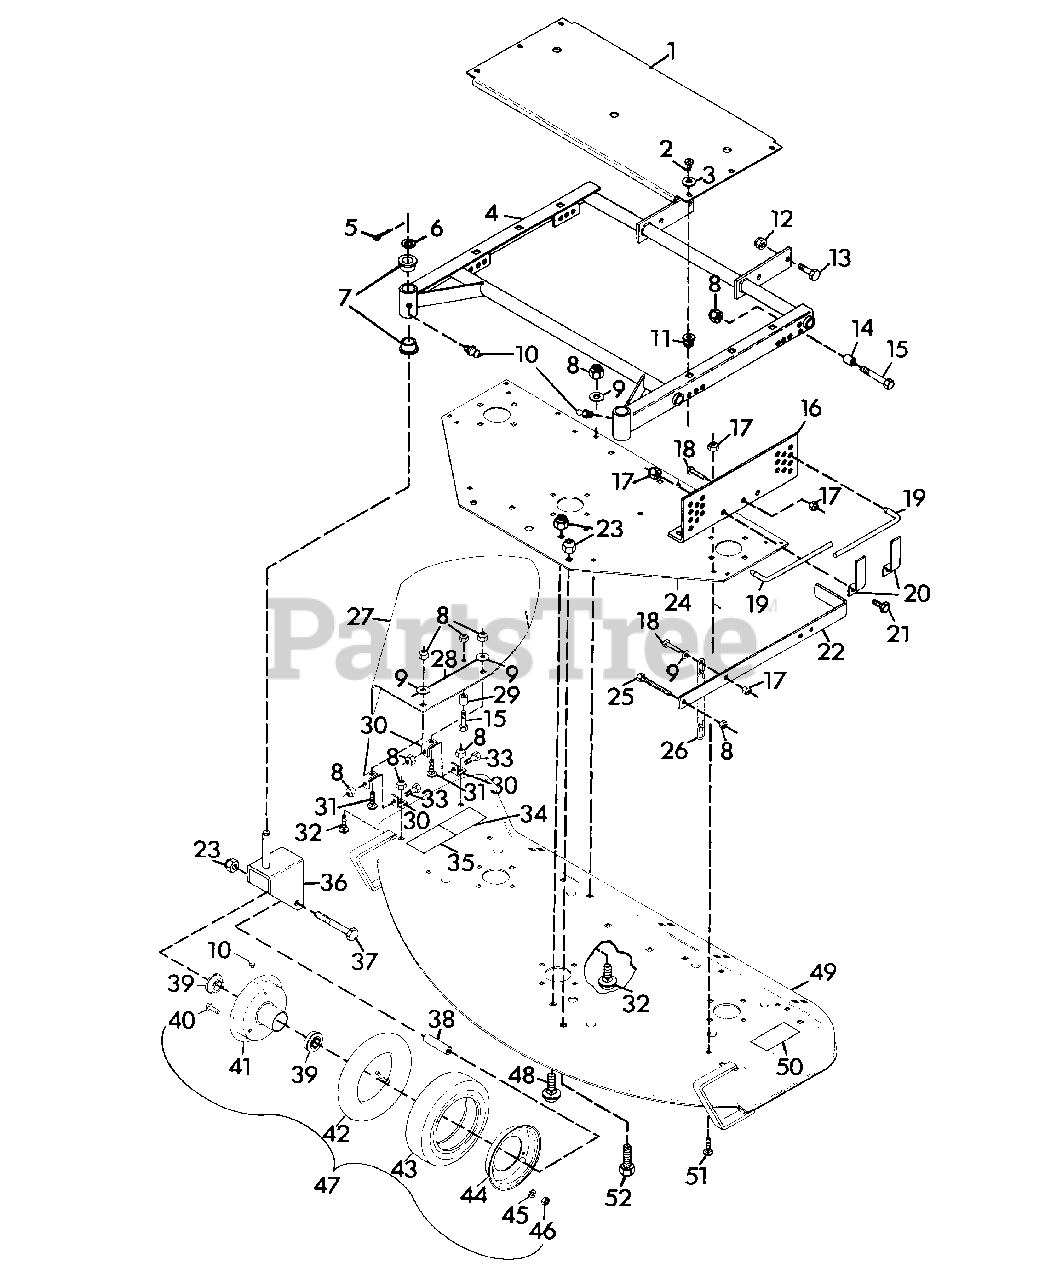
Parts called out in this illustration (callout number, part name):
1	GUARD, 50" MOWER BELT
2	SCREW, TAPPING 1/4-20X.625 P/HD
3	WASHER, FLAT .281X.625X.065
4	WELDMENT, MOWER FRAME
5	PIN, COTTER .187X1.50
6	RACE, BEARING THRUST
7	BUSHING, PIVOT
8	NUT, LOCK 3/8-16
9	WASHER, FLAT .406X.812X.065
10	FITTING, LUBE 1/4-28
11	GROMMET, PLASTIC
12	NUT, LOCK 5/8-11
13	BOLT, HEX 5/8-11X1.50
14	BUSHING .391X.622X.670
15	BOLT, HEX 3/8-16X1.50
16	BRACKET, MOWER SUPPORT L.H.
16	BRACKET, MOWER SUPPORT R.H.
17	NUT, LOCK 5/16-18
18	BOLT, HEX 5/16-18X1.00
19	PIN, MOWER LOCKING
20	TAB, PIN LOCKING
21	BOLT, HEX 5/16-18X.75
22	BAR, LIFT
23	NUT, LOCK 1/2-13
24	ASSEMBLY, 50" SUPPORT PLATE
25	BOLT, HEX 3/8-16X2.00
26	CHAIN, HEIGHT ADJUSTMENT
27	SHIELD, SAFETY EXT. 50" MOWER
28	STRIPE
29	STOP, CHUTE
30	TAB, SPRING
31	BOLT, 3/8-16X1.00 RD HD SQ NK
32	BOLT, CARRIAGE 3/8-16X.75
33	BOLT, HEX 3/8-16X.875
34	DECAL, DANGER HAND
35	DECAL, WARNING EYE
36	WELDMENT, CASTER FORK
37	BOLT, HEX 1/2-13X5.00
38	BUSHING, WHEEL .520X.750X3.312
39	BEARING, GAUGE WHEEL
40	BOLT, HEX 3/8-24X.75
41	WHEEL, HALF WITH TUBE
42	TUBE, INNER
43	TIRE, GAUGE WHEEL
44	WHEEL, HALF PLAIN
45	WASHER, LOCK 3/8 SP HEAVY
46	NUT, HEX 3/8-24
47	WHEEL, GAUGE
48	BOLT, 1/2-13X1.00 RD HD SQ NK
49	WELDMENT, 50" DECK
50	DECAL, DANGER FOOT
51	BOLT, CARRIAGE 5/16-18X1.00
52	BOLT, HEX 1/2-13X1.25
NS	DECAL, GRAVELY LOGO
NS	DECAL, PRO-50
NS	BAFFLE
